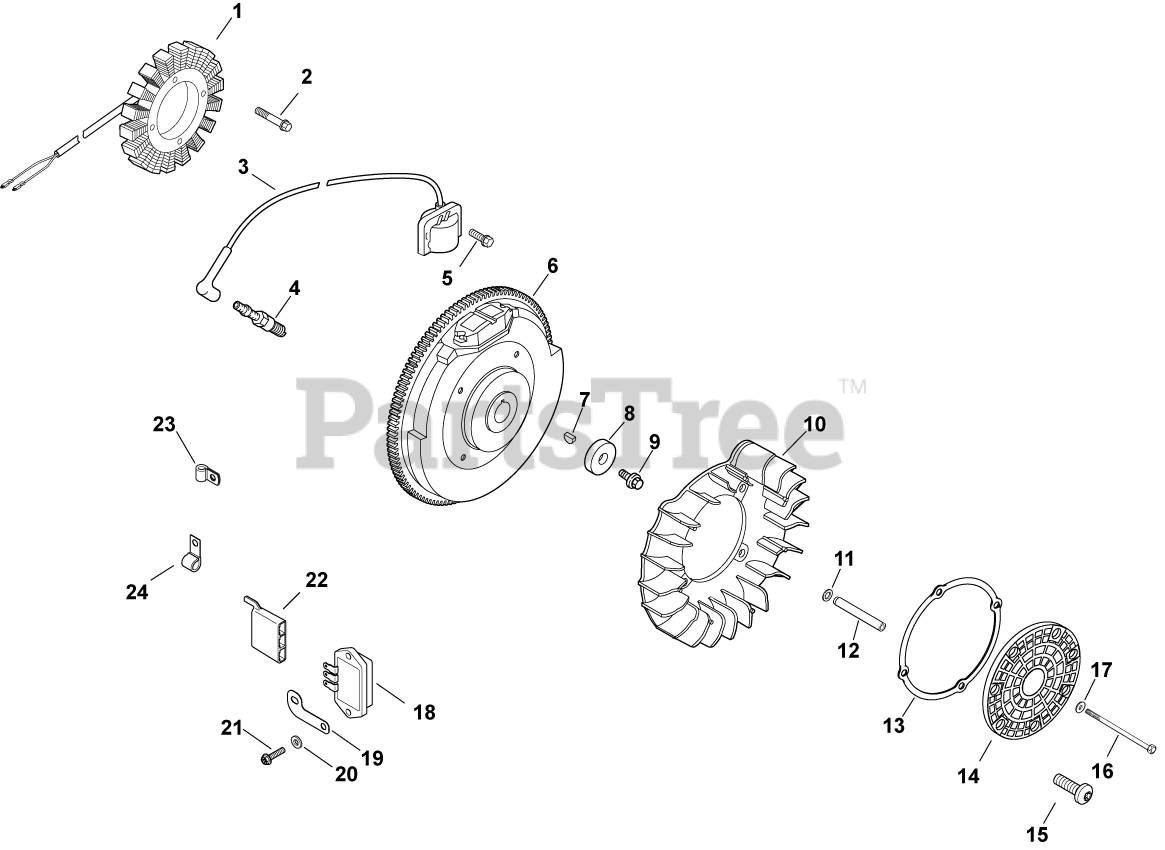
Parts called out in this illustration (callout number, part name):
1	KIT, 15 / 20 AMP STATOR
2	SCREW, M5X0.8X25 - (#25086402S)
3	KIT, MODULE IGNTN (CDI FIXED)
4	PLUG, SPARK (PRO SERIES)
5	SCREW, FLG THD FRM M5X.8X20-(#25086399S)
7	KEY, 3/16" X 5/8"
8	WASHER, FLAT 13/32"
9	SCREW, FLG M10X1.5X45 - (#25086361S)
10	FAN USE 24 755 253-S
11	WASHER, SPRING 10 MM
13	RING, SUPPORT USE 25 141 08-S
14	SCREEN, GRASS
15	SCREW, SKT SET #10-24X1/4"
16	SCREW, SOCKET TRUSS HD CAP
17	WASHER, FLAT 1/4" (O.D. 5/8")
18	REG/RECT-15 AMP (KM)-USE 41 403 10-S
19	BRACKET, GROUND STRAP USE 24 518 12-S
20	WASHER, FLAT 1/4" (O.D. 1/2")
21	SCREW, HEX FLANGE HI-LO
22	CONNECTOR
23	CLIP, CABLE
